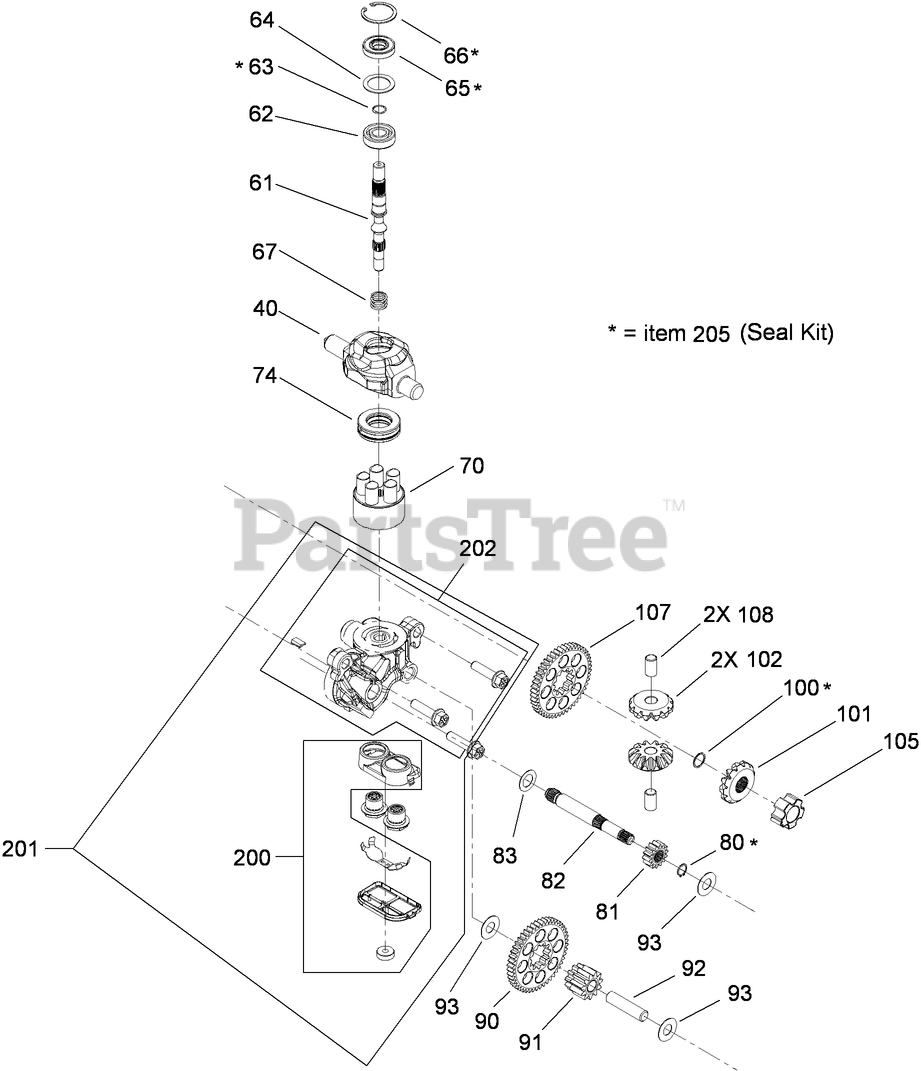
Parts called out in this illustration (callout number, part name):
40	TRUNNION-PLATE, SWASH
61	SHAFT-INPUT
62	BEARING-SHAFT, BALL
63	RING-WIRE, RETAINING
64	SPACER
65	SEAL-LIP
66	RING-RETAINING
67	SPRING-HELICAL
70	CYLINDER BLOCK KIT
74	BEARING-THRUST, BALL
80	RING-RETAINING, EXTERNAL
81	GEAR-PINION, 13T
82	SHAFT-MOTOR
83	WASHER
90	GEAR-11T/48T
91	GEAR-JACKSHAFT, 11T
92	PIN-JACKSHAFT
93	WASHER
100	RING-RETAINING, SPIRAL
101	GEAR-BEVEL, 12T (SPLINE, ID)
102	GEAR-BEVEL, 12T (.50 ID)
105	BUSHING-INBOARD
107	GEAR-53T, BULL
108	PIN-DIFFERENTIAL
200	FILTER KIT
201	CENTER SECTION W/FILTER KIT
202	CENTER SECTION KIT
205	SEAL KIT
